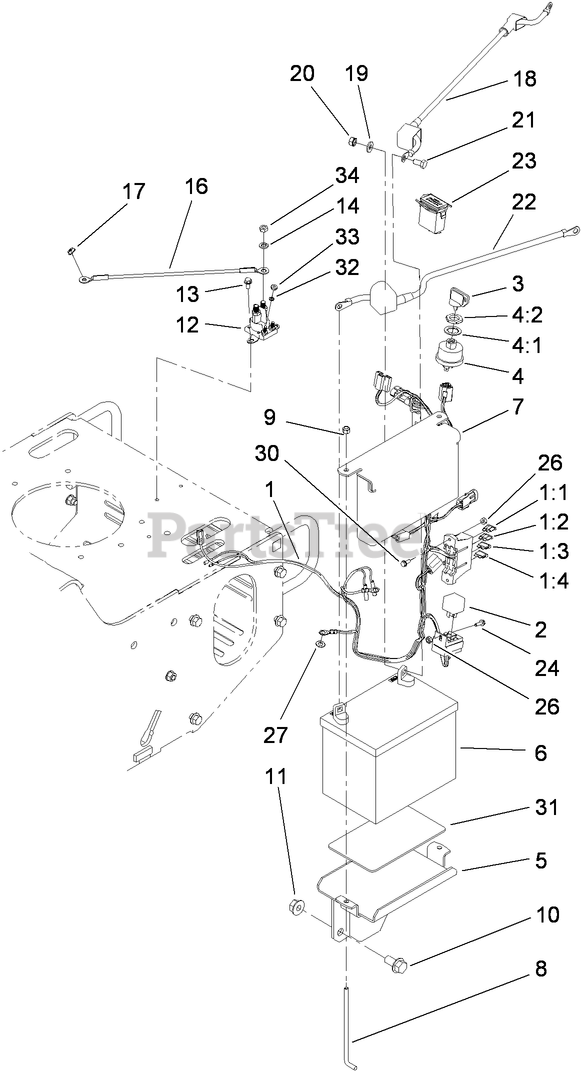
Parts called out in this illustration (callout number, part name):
1	HARNESS-WIRE
1:1	FUSE-BLADE, 30 AMP
1:2	FUSE-BLADE, 25 AMP
1:3	FUSE-BLADE, 15 AMP
1:4	CAP-PLUG
2	RELAY
3	KEY-IGNITION
4	Key Switch ASM
4:1	WASHER-TOOTH, INTERNAL
4:2	NUT-HH
5	TRAY-BATTERY
6	BATTERY-DRY
7	PLATE-HOLD DOWN, BATTERY
8	HOLDOWN-BATTERY
9	NUT-LOCK, NI
10	SCREW-HHF
11	NUT-HHF
12	SOLENOID
13	SCREW-HWH
14	WASHER-LOCK
16	WIRE-SOLENOID/STARTER
17	NUT-KEPS
18	CABLE-BATTERY, RED
19	WASHER-FLAT
20	NUT-KEPS
21	SCREW-HH
22	CABLE-BATTERY, BLACK
23	METER-HOUR
26	NUT-LOCK, NI
27	WASHER-LOCK
30	SCREW-HWH
31	PAD-SKID, ANTI
32	WASHER-LOCK
33	NUT-HEX
34	NUT-JAM
